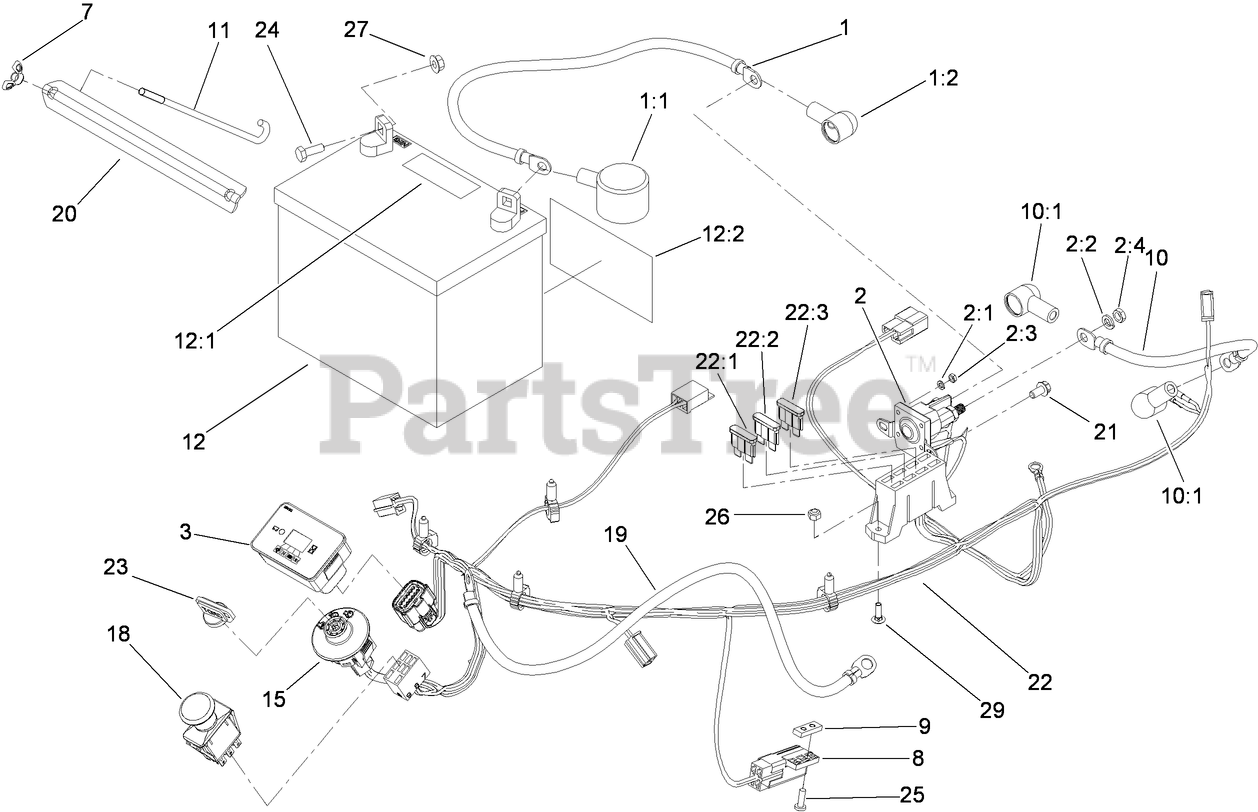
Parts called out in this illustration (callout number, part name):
1	POSITIVE BATTERY CABLE ASM
1:1	INSULATOR-BATTERY
1:2	INSULATOR-SOLENOID
2	SWITCH-SOLENOID
2:1	WASHER-LOCK
2:2	WASHER-LOCK
2:3	NUT-HEX
2:4	NUT-JAM
3	HOUR METER ASM
7	WINGNUT
8	SWITCH
9	PLATE-TAPPED
10	POSITIVE STARTER CABLE ASM
10:1	INSULATOR-SOLENOID
11	BOLT-HOLDDOWN
12	BATTERY
12:1	Decal-Battery
12:2	Decal-Battery
15	SWITCH-IGNITION
18	SWITCH-PTO
19	CABLE-BATTERY, NEGATIVE
20	ANGLE-BATTERY
21	SCREW-HWH
22	HARNESS-WIRE
22:1	FUSE-BLADE, 30 AMP
22:2	FUSE-BLADE, 25 AMP
22:3	FUSE-BLADE, 10 AMP
23	KEY-IGNITION
24	SCREW-HH
25	SCREW-PPH
26	NUT-LOCK, NI
27	NUT-HF
29	BOLT-CARR
